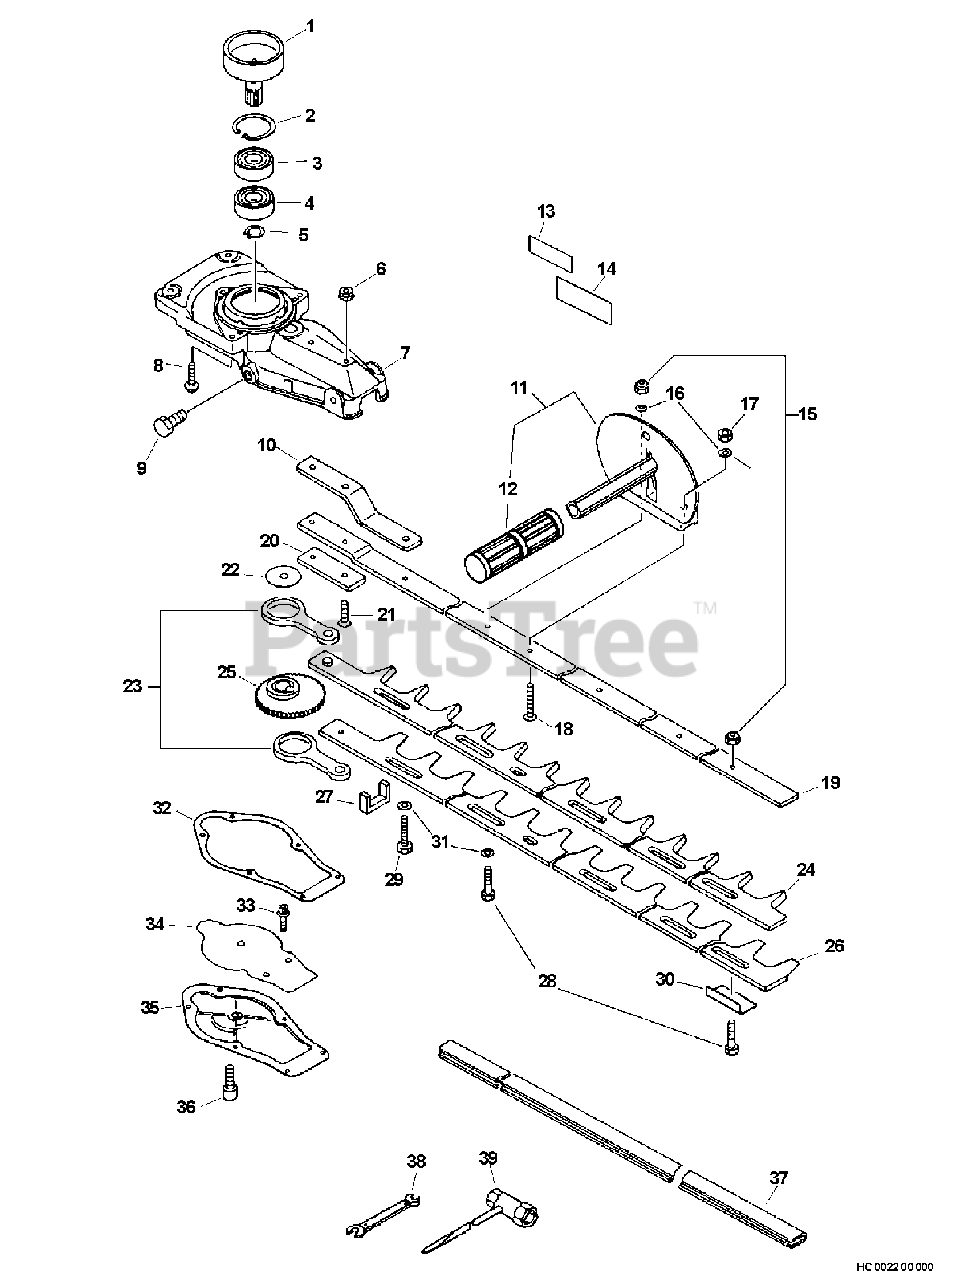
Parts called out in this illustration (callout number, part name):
1	DRUM, CLUTCH
2	RING, RETAINING - 35
3	BEARING, BALL - 6202
4	BEARING, BALL - 6202
5	RING, RETAINING - 14
6	LOCKNUT - 6
7	CASE, GEAR - UPPER
8	SCREW - 5X25
9	BOLT - 8X8
10	PLATE, ANGLE
11	HANDLE ASSY - FRONT
12	GRIP, HANDLE
13	LABEL - CAUTION
14	LABEL - CAUTION
15	LOCKNUT - 6
17	LOCKNUT - 6
18	SCREW - 6X30
19	SUPPORT, BLADE
21	SCREW - 6X25
23	ROD, CONNECTING
24	BLADE - UPPER
25	GEAR - DRIVE
26	BLADE - LOWER
27	SEAL, FELT
28	BOLT - 6X22
29	BOLT - 6X35
30	INSULATOR
31	WASHER - 6
32	GASKET, GEAR CASE
33	SCREW - 5X12
34	LID, GEAR CASE
35	LID, GEAR CASE - LOWER
36	SCREW - 4X12
37	COVER, BLADE
38	SPANNER - 8X10mm
39	T-WRENCH - 13X19mm
